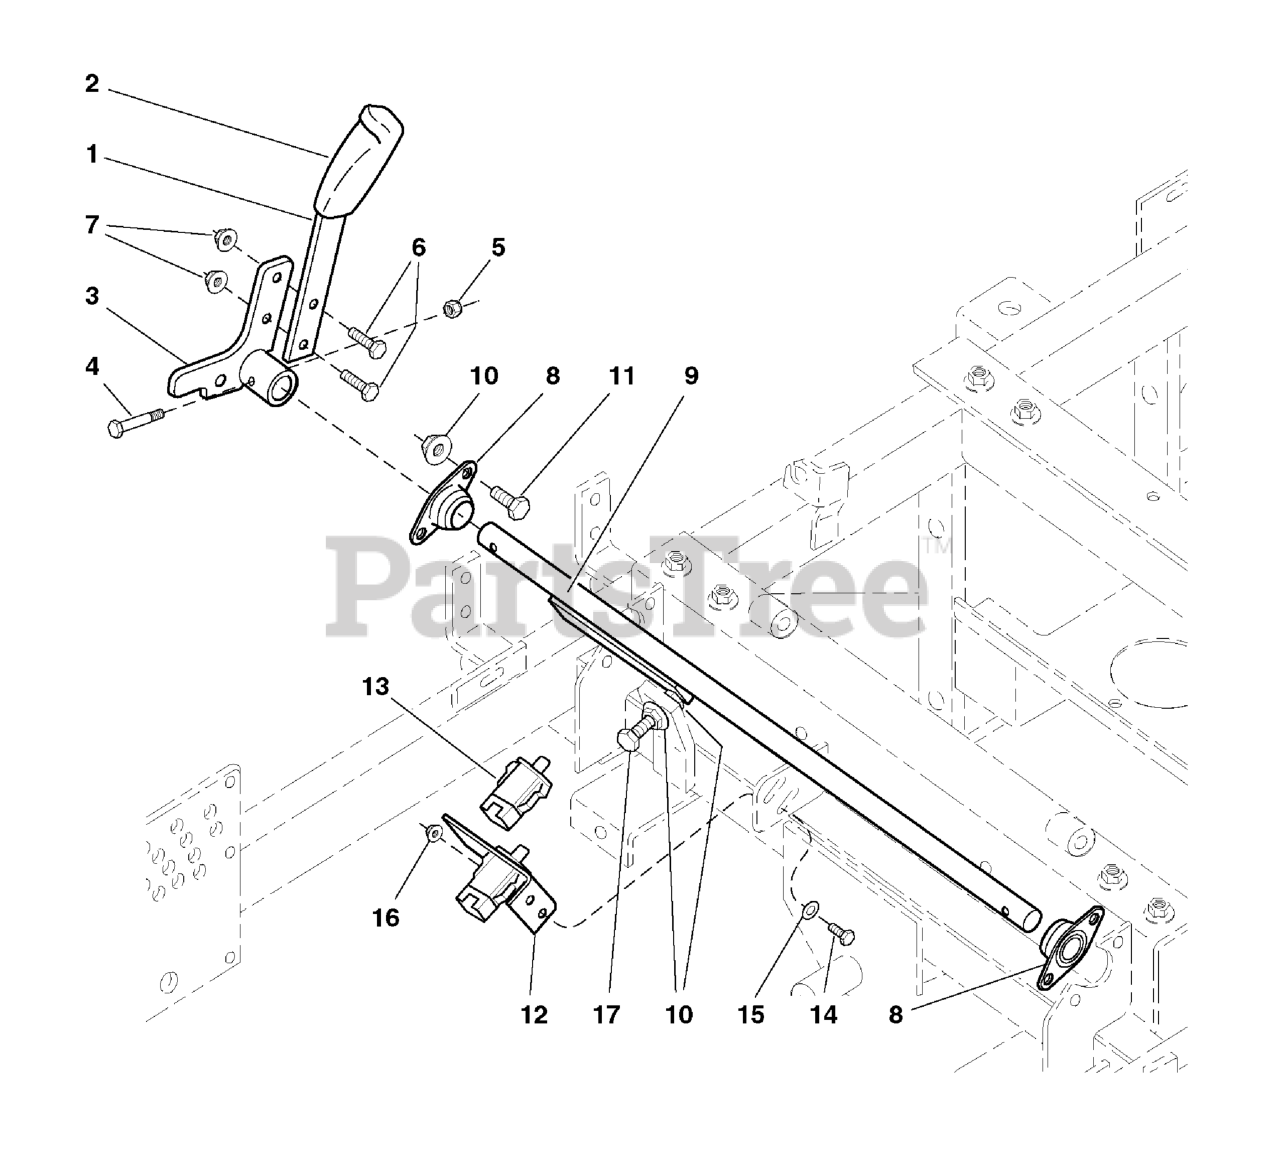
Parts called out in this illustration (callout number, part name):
1	BRAKE HANDLE
2	GRIP
3	BRAKE HANDLE MOUNT
4	BOLT, 1/4-20 x 1-3/4
5	NUT, 1/4-20 HEX NYLON LOCK
6	BOLT, 5/16-18 X 1 GD5 YZ
7	NUT, 5/16-18 HEX SERRATED FLANGE (SMALL)
8	BEARING, Flange
9	BRAKE HANDLE SHAFT
10	NUT, 3/8-16 Hex Serrated Flange
11	BOLT, 3/8-16 X 3/4" GD5 CZ
12	SWITCH MOUNT BRACKET
13	SWITCH, DP NO/NC SNAP-IN
14	BOLT, 1/4-20 x 3/4
15	WASHER, 1/4 SAE
16	NUT, 1/4-20 HEX SERR. FLANGE
17	BOLT, 3/8-16 x 1-3/4 TFL
